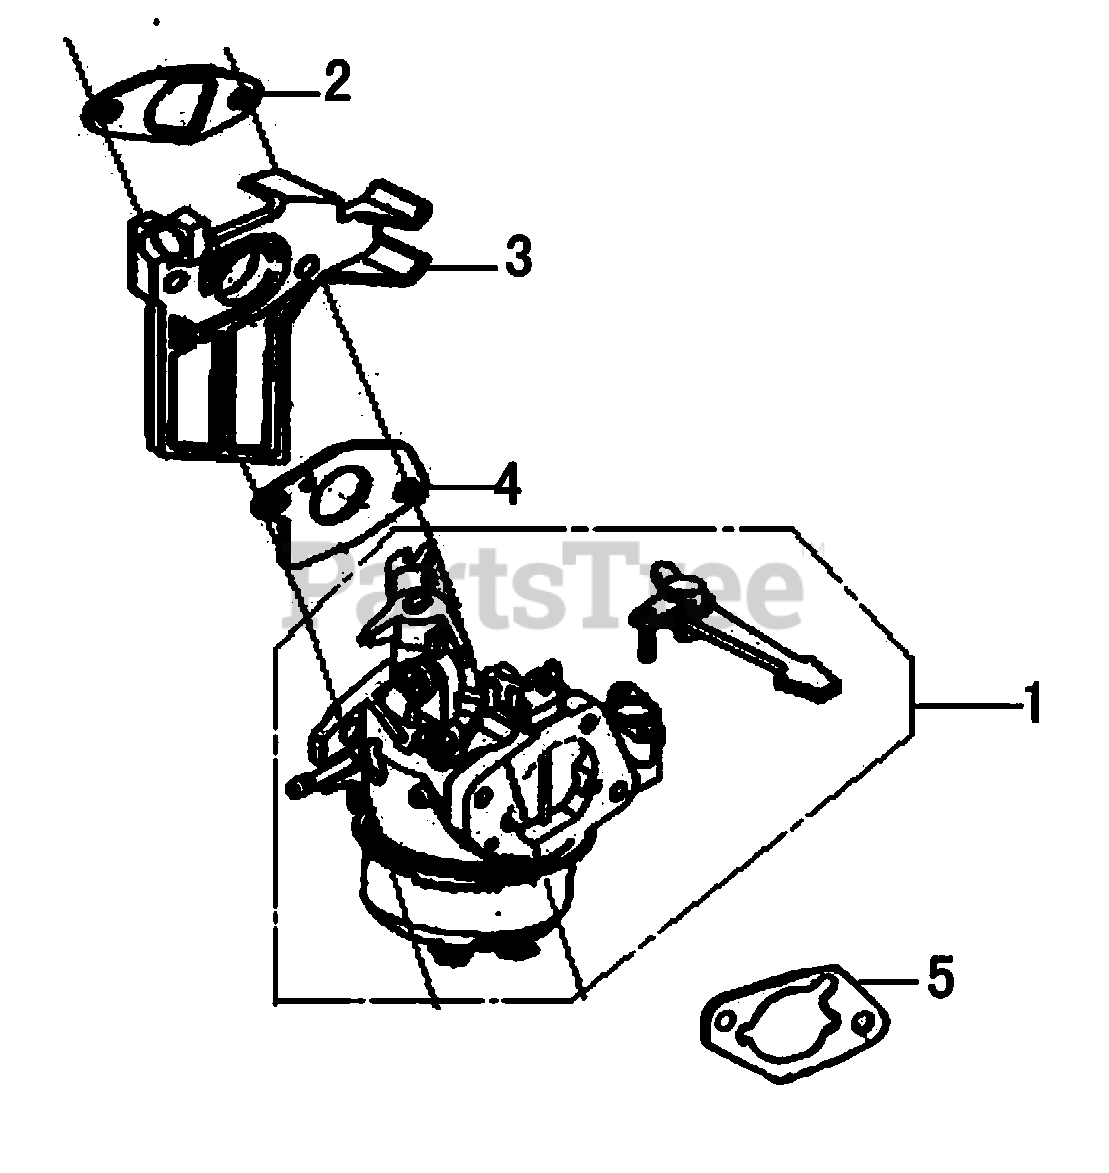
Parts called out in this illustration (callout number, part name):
1	CARBURETOR
2	GASKET, INSULATOR
3	INSULATOR,CARBURETOR
4	GASKET, CARBURETOR
5	GASKET, AIR CLEANER
